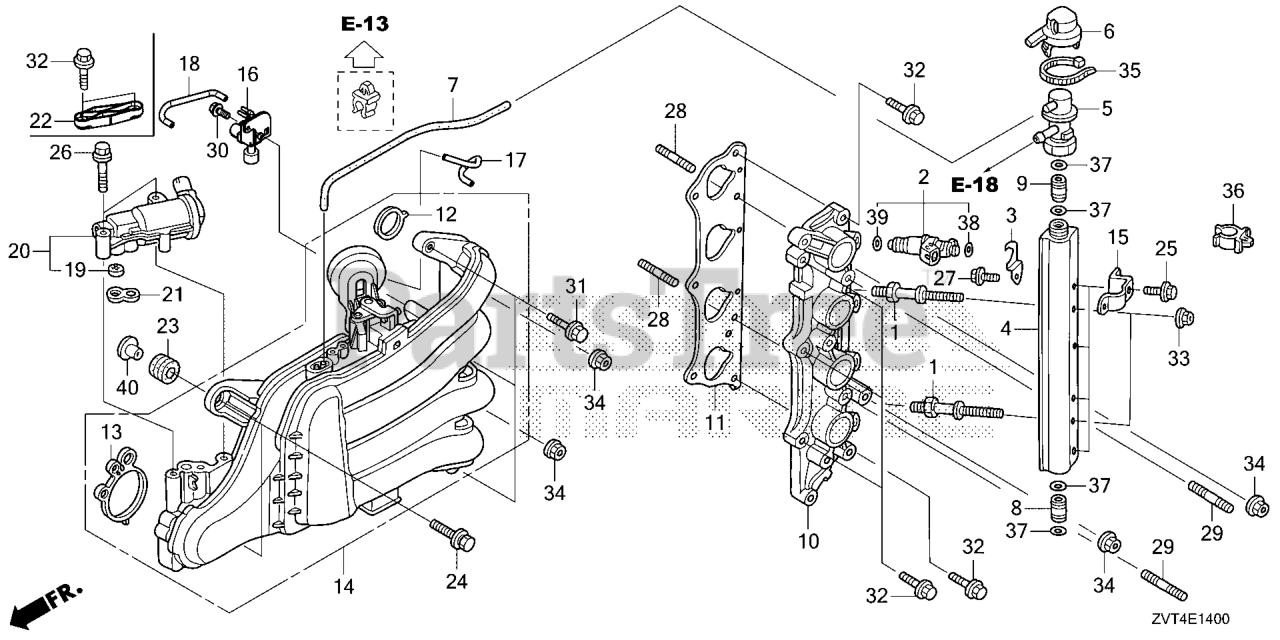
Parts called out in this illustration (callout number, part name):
1	BOLT, FUEL PIPE
2	INJECTOR ASSY., FUEL
3	CLIP, INJECTOR
4	LINE, FUEL
5	REGULATOR ASSY., PRESSURE
6	CAP, REGULATOR
7	TUBE, PRESSURE REGULATOR CONTROL
8	JOINT, FUEL PIPE
9	JOINT, FUEL PIPE
10	BASE, INJECTOR *NH8* (DARK GRAY)
11	GASKET A, INJECTOR BASE
12	GASKET, IN. MANIFOLD
13	GASKET, THROTTLE BODY
14	MANIFOLD, IN.
15	BRACKET A, HARNESS CLIP
16	VALVE ASSY., AIR BYPASS
17	TUBE, DIAPHRAGM
18	TUBE, BYPASS SOLENOID
19	FILTER, ELECTRONIC AIR CONTROL VALVE (TOYO ROKI)
20	VALVE ASSY., ELECTRONIC AIR CONTROL
21	GASKET, ELECTRONIC AIR CONTROL VALVE
23	RUBBER, FR. CARRIER CUSHION
24	BOLT-WASHER (8X35)
25	BOLT, FLANGE (6X14)
26	BOLT, FLANGE (8X45)
27	BOLT (6X10)
28	BOLT 2, STUD (8X25)
29	BOLT, STUD (8X32)
30	BOLT, FLANGE (5X12)
31	BOLT, FLANGE (8X35)
32	BOLT, FLANGE (8X25)
33	NUT, FLANGE (6MM)
34	NUT, FLANGE (8MM)
35	BAND, HARNESS
36	CLIP, FUEL TUBE (14) (NOT AVAILABLE)
37	O-RING (7.8X1.9) (ARAI)
38	O-RING (7.47X3.6)
39	O-RING (7.45X3.61) (NOK)
40	COLLAR (8.5X14.5)
